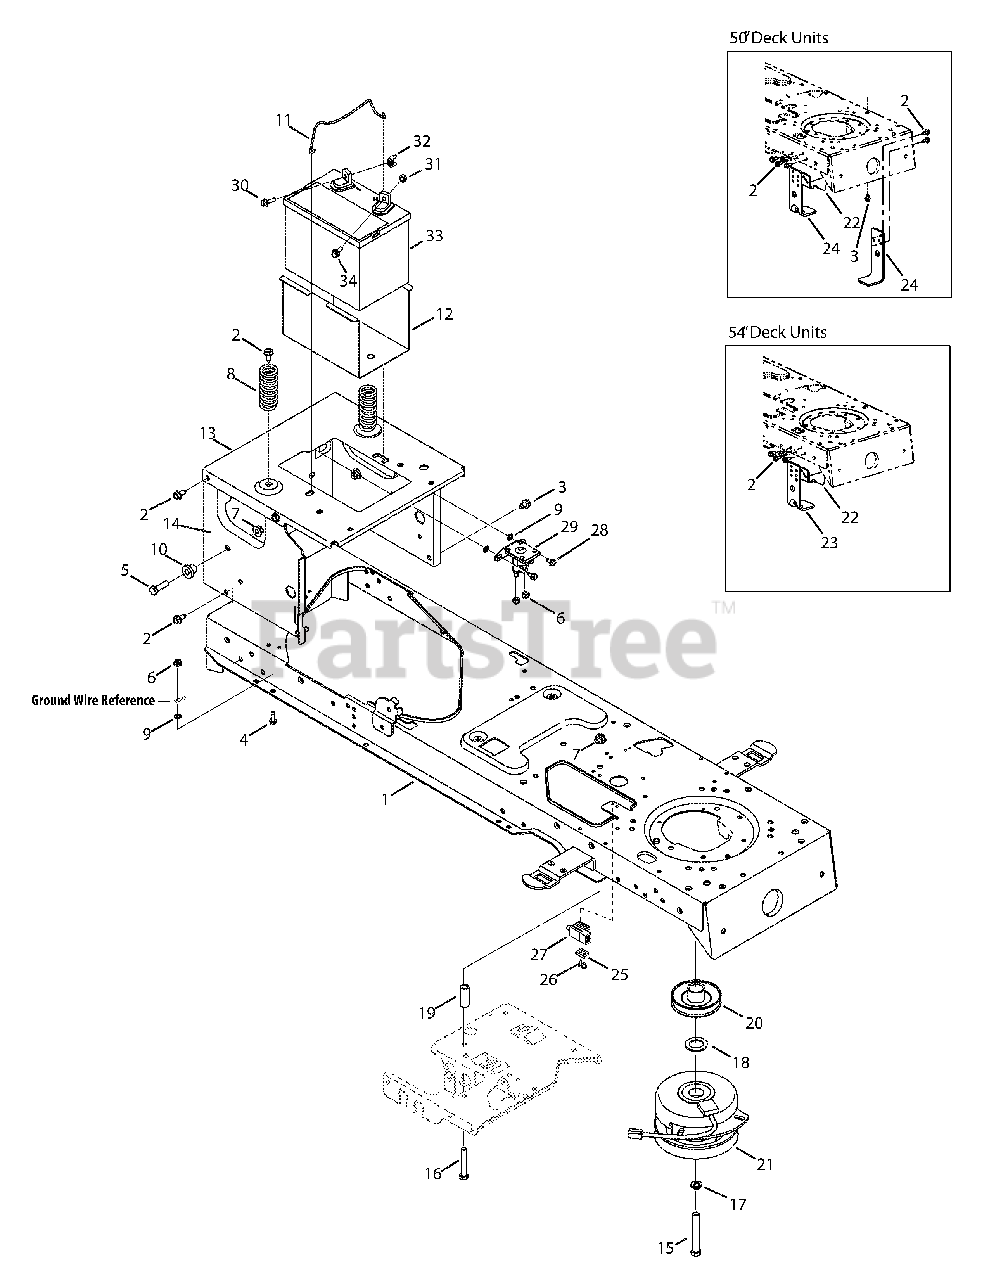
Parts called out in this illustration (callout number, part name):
3	Screw, 5/16-18, 0.500
4	Screw, 1/4-20, 0.750
5	Screw, 3/8-16, 1.25, Gr5
6	Nut, Flange Lock, 1/4-20
7	Nut, Flange Lock, 3/8-16
8	Spring, Compress., 1.28 x 3.125
9	Washer, Lock, 1/4, External
10	Spacer, Shoulder,.38 x 1.0 x.70
11	Hold Rod, Battery
15	Screw, 7/16-20, 3.50, Gr5, Lock
16	Screw, 3/8-16, 2.25, Gr5
17	Lock Washer, 7/16
18	Washer, Flat, 1.031 x 1.620 x.095
19	Spacer,.385 ID x.635 OD x 1.54
20	Pulley, Engine, 3.56 Diameter
21	PTO Clutch, Electric
26	AB Screw, #10-16 x.500
27	Switch
28	Screw, 1/4-20, 0.50
29	Solenoid, 12V, 100 Amp
30	Hex Flange Bolt, 1/4-20,.75
31	Nut, Sems, 1/4-20
32	Nut, Wing, 1/4-20
33	Battery, 235 CCA
34	Screw, Shoulder,.250 x.15, 1/4-20
